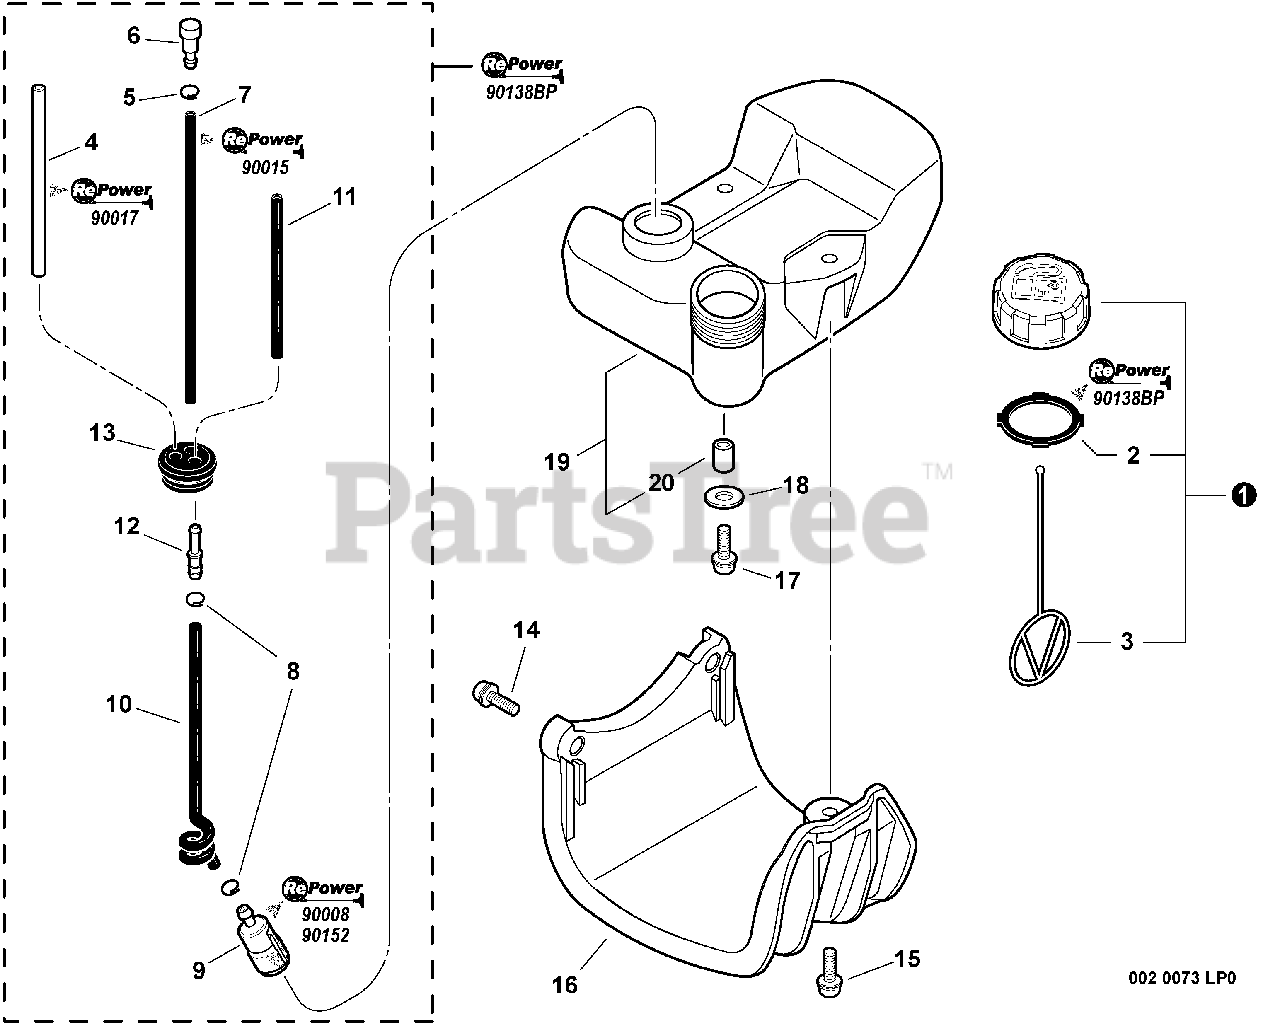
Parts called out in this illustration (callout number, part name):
1	CAP ASSY, FUEL
2	GASKET, FUEL CAP
3	CONNECTOR, CAP L= 100 MM
4	PIPE, FUEL 3×6×80 CLEAR
5	CLIP Ø6.5 MM
6	VENT ASSY
7	PIPE 3×6×115 BLACK
8	CLIP Ø6.5 MM
9	FILTER, FUEL
10	PIPE, FUEL 3×6×105
11	PIPE, FUEL 3×5×74 BLACK
12	CONNECTOR, PIPE Ø5ר3.5
13	GROMMET, FUEL
14	BOLT 5×22
15	SCREW 5×20
16	GUARD, FUEL TANK
17	BOLT 5×16
18	WASHER 5.5×12×0.8
19	TANK, FUEL
20	SPACER 6.2×7.8×6
21	FUEL SYSTEM KIT
22	TUNE-UP KIT - REPOWER
23	FILTER KIT - REPOWER
24	BULK PIPE - 3×6 MM BLACK (4 PIECES×2 M)
25	BULK PIPE - 3×6 MM CLEAR (4 PIECES×2 M)
